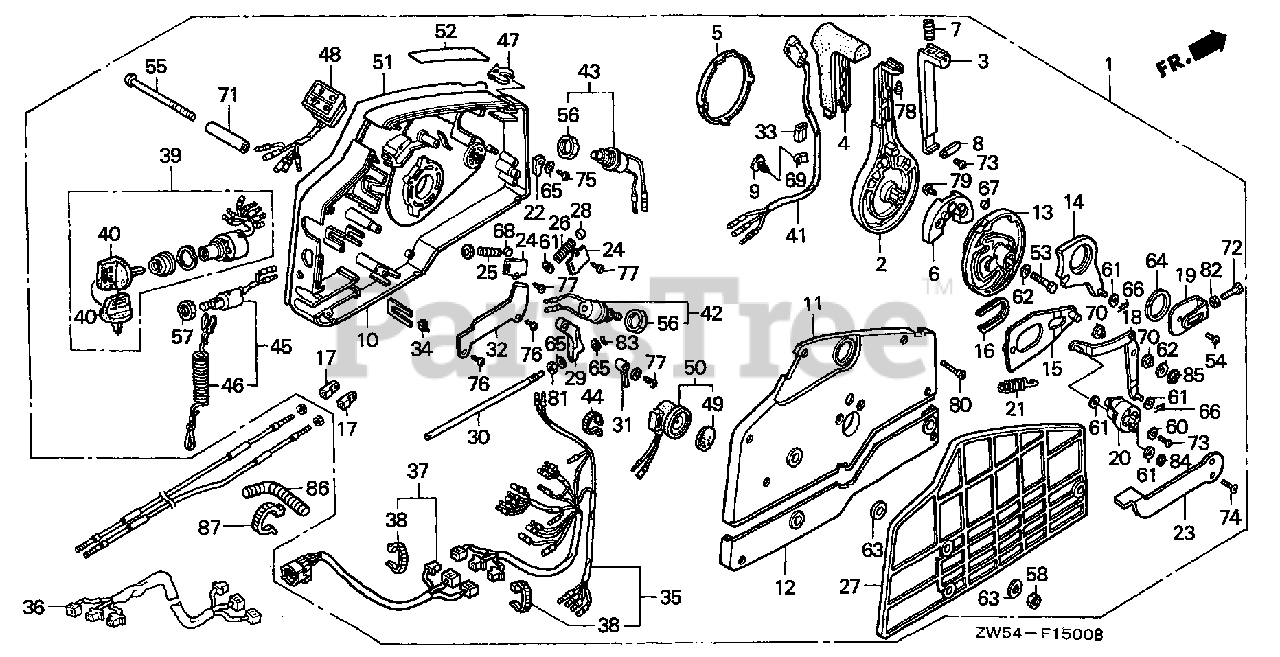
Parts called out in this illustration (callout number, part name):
1	BOX ASSY., REMOTE CONTROL
2	HANDLE, REMOTE CONTROL
3	LEVER, HANDLE LOCK
4	GRIP, REMOTE CONTROL HANDLE
5	CAP, HANDLE
6	BLOCK, NEUTRAL LOCK
7	SPRING, REMOTE CONTROL HANDLE
8	PLATE, LEVER SETTING
9	CLAMP, HARNESS
10	HOUSING, REMOTE CONTROL BOX
11	HOUSING, REMOTE CONTROL BOX
12	HOUSING, REMOTE CONTROL BOX
13	WHEEL, CONTROL
14	ARM, SHIFT LINK
15	PLATE, SLIDING
16	COLLAR, SLIDING PLATE
17	PIVOT, SHIFT
18	ARM, LINK JOINT
19	BRACKET, LINK JOINT
20	WHEEL, ACCELERATOR
21	SPRING, ACCELERATOR WHEEL
22	CAM, STARTER SWITCH
23	LEVER, IDLE
24	PLATE, SPRING SETTING
25	SPRING, SHIFT CLICK
26	SPRING, CHOKE RETURN
27	SPACER, REMOTE CONTROL BOX
28	SPACER, CLICK SPRING
29	BLOCK, THROTTLE FRICTION
30	BOLT, FRICTION
31	SPACER, NEUTRAL SWITCH
32	CLAMP, POWER TILT CORD
33	PIPE, HARNESS GUIDE
34	SPACER, CABLE CLAMP
35	CABLE ASSY., REMOTE CONTROL
36	CABLE ASSY., REMOTE CONTROL
37	CABLE ASSY., SWITCH PANEL
38	TIE, CABLE (NATURAL 2.4X92)
39	SWITCH ASSY., COMBINATION
40	KEY ASSY., COMBINATION SWITCH
41	SWITCH ASSY., POWER TRIM-TILT
42	SWITCH ASSY., THROTTLE
43	SWITCH ASSY., SOLENOID
44	BAND (BLACK 3.5X140)
45	SWITCH ASSY., EMERGENCY STOP
46	WIRE, EMERGENCY
47	CLIP, EMERGENCY LOCK
48	LAMP ASSY., INDICATION (2-LED)
49	PLATE, TURN SIGNAL BUZZER
50	BUZZER, WARNING
51	PLATE, REMOTE CONTROL
52	MARK, FAST IDLE
53	BOLT, HEX. (8X35)
54	SCREW, PAN (6X10)
55	SCREW (6X95)
56	NUT, HEX. (20MM)
57	NUT, HEX. (16MM)
58	NUT, HEX. (6MM)
60	WASHER, PLAIN (5MM)
61	WASHER, PLAIN (6MM)
62	WASHER, PLAIN (8MM)
63	WASHER (6MM)
64	WASHER (28MM)
65	WASHER, PLAIN (4MM)
66	PIN, LOCK (6MM)
68	ROLLER, CLICK
69	CLIP, WIRE HARNESS (6.3MM)
70	COLLAR, LINK JOINT
71	COLLAR, DISTANCE (6X10X43.5)
72	BOLT, HEX. (5X16)
73	SCREW, PAN (5X10)
74	SCREW, OVAL (5X12)
75	SCREW, TAPPING (4X10)
76	SCREW, TAPPING (5X8)
77	SCREW, TAPPING (5X10)
78	SCREW, TAPPING (5X12)
79	SCREW, TAPPING (6X16)
80	SCREW, TAPPING (5X25)
81	NUT, HEX. (6MM)
82	NUT, HEX. (5MM)
83	E-RING (3MM)
84	E-RING (4MM)
85	E-RING (7MM)
86	TUBE, CORRUGATE (28MM)
87	BAND, SELF-LOCK
